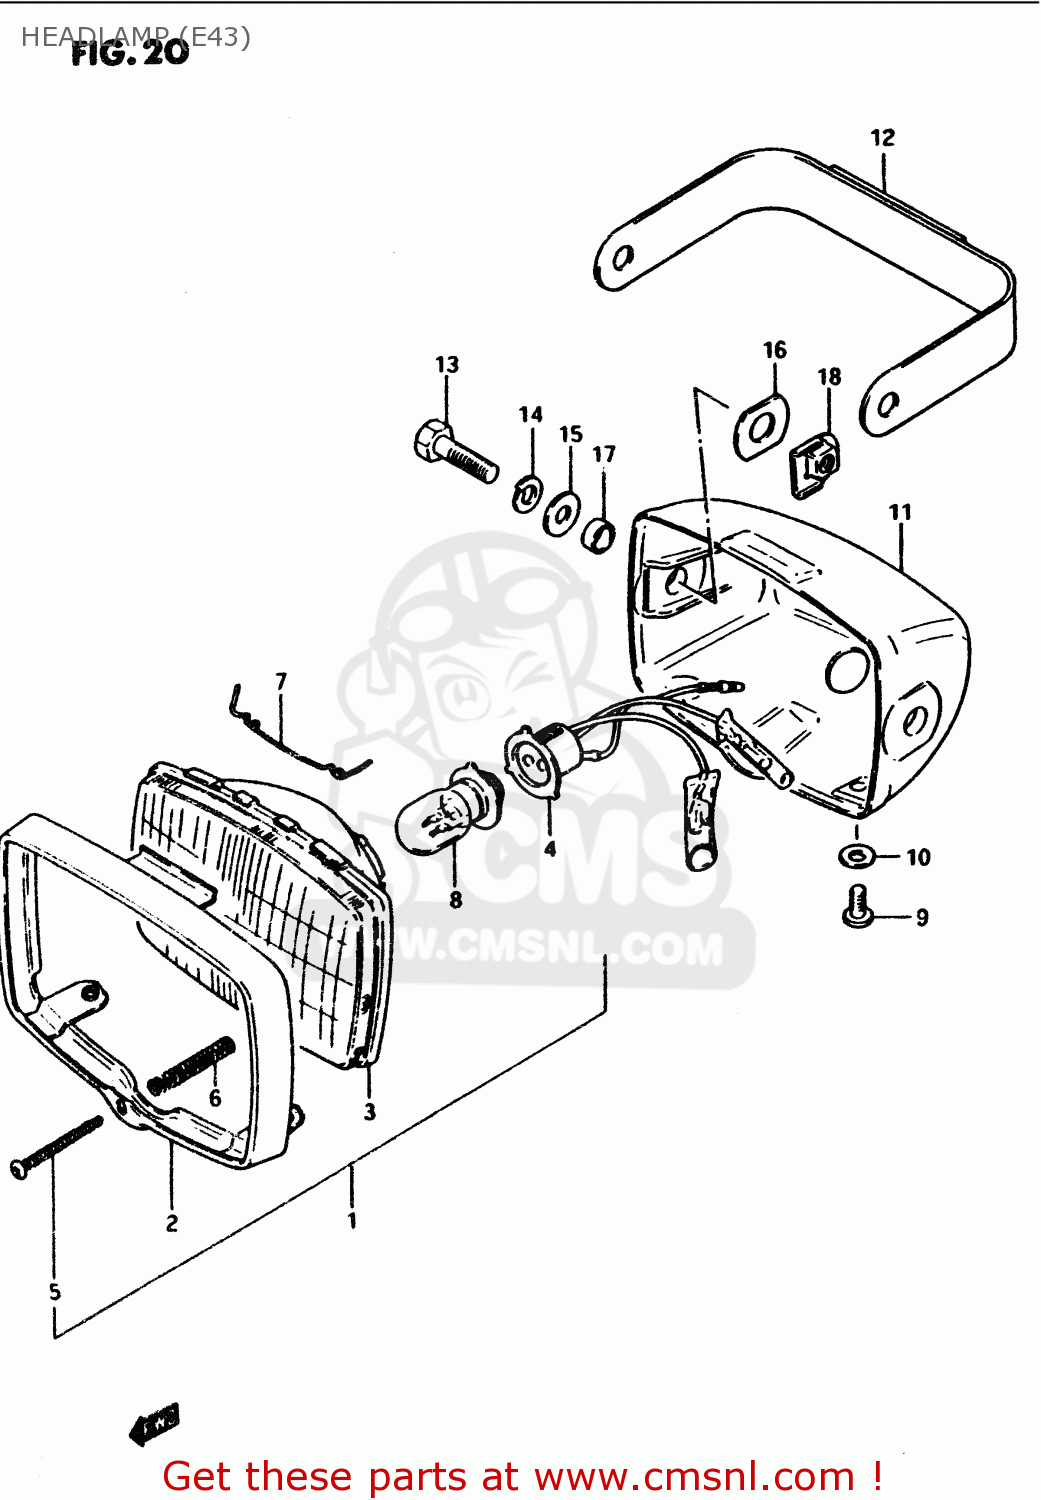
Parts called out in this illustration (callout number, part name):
1	LYKT KOMPL E16
2	RIM
3	LAMP UNIT
4	SOCKET,HEADLAMP
5	SCREW,HEADLAMP ADJUST
6	SPRING,HEAD LAMP ADJUSTER
7	SPRING,HEADLAMP UNIT
8	PARE
9	SCREW
10	WASHER
11	HOUSING,HEADLAMP(BLACK)
12	BRACKET,HEAD LAMP HOUSING
13	BOLT
14	LOCK WASHER
15	WASHER
16	CUSHION
17	SPACER (8.8X12X7)
18	PLATE,HEADLAMP HOUSING
